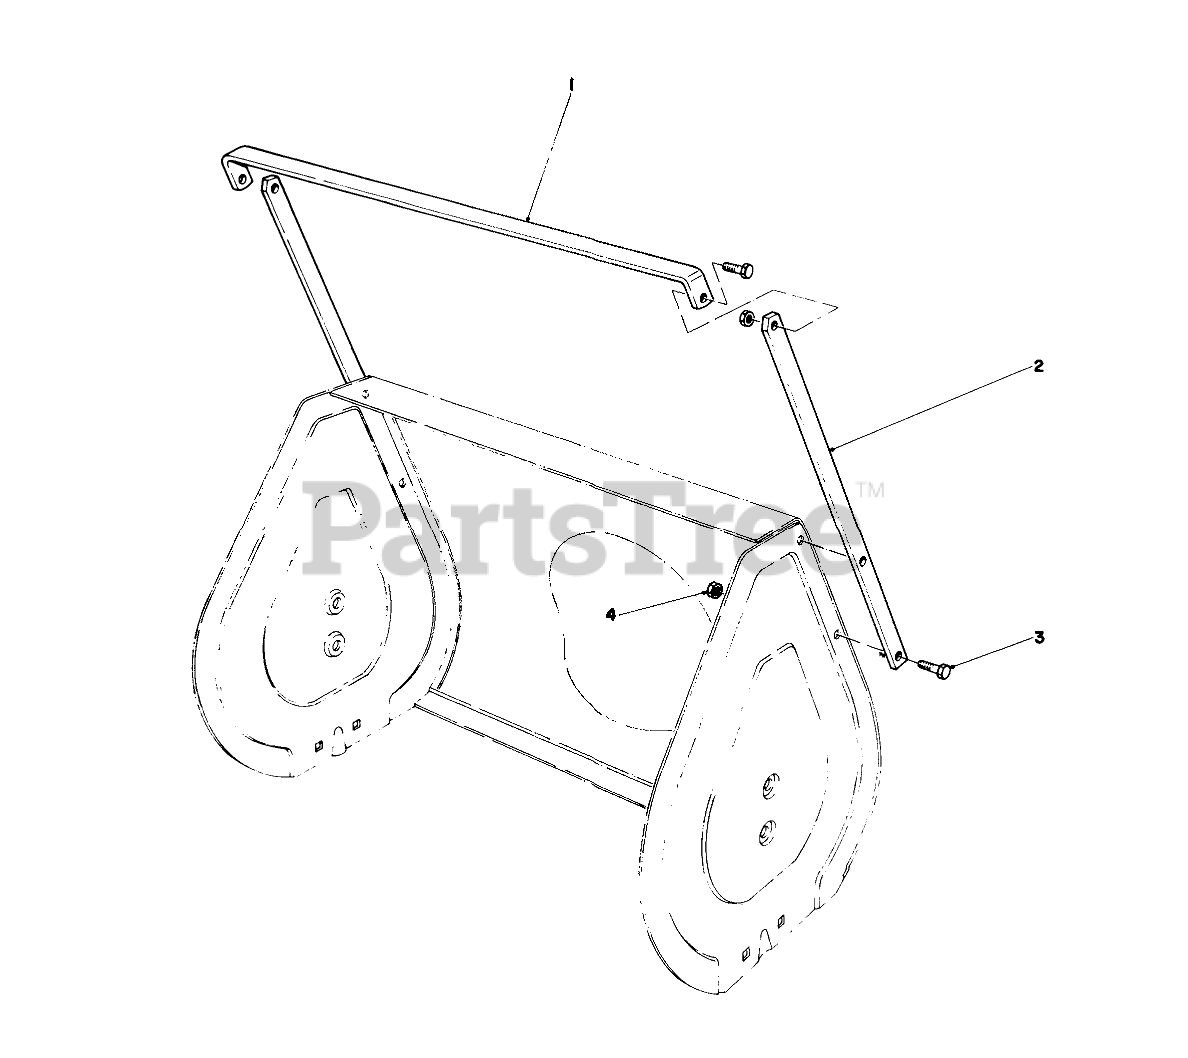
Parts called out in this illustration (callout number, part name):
1	Drift Breaker-Top
2	Drift Breaker-Side
3	Screw
4	NUT-LOCK, NI
